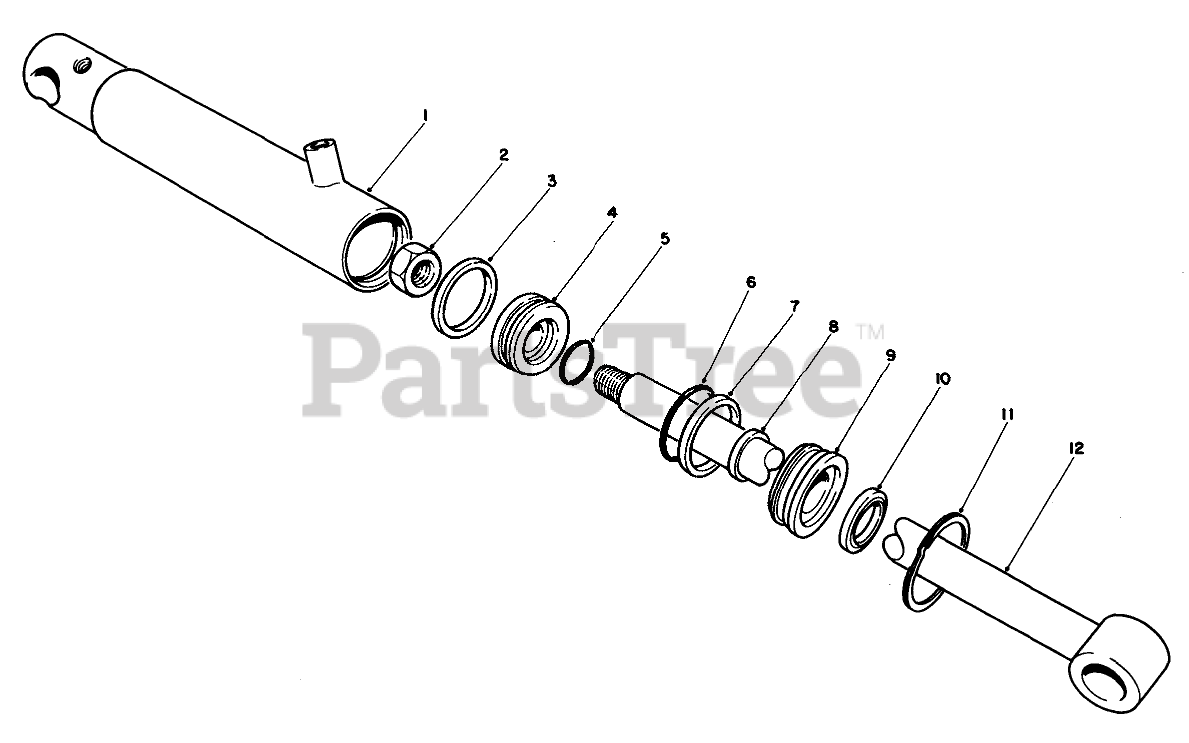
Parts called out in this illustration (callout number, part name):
1	Tube Assembly
2	LOCKNUT
4	PISTON
6	O-Ring Head
7	Back Up
8	Poly-Pack
10	Dust Seal
11	RING-RETAINING
12	SHAFT W/CLEVIS
